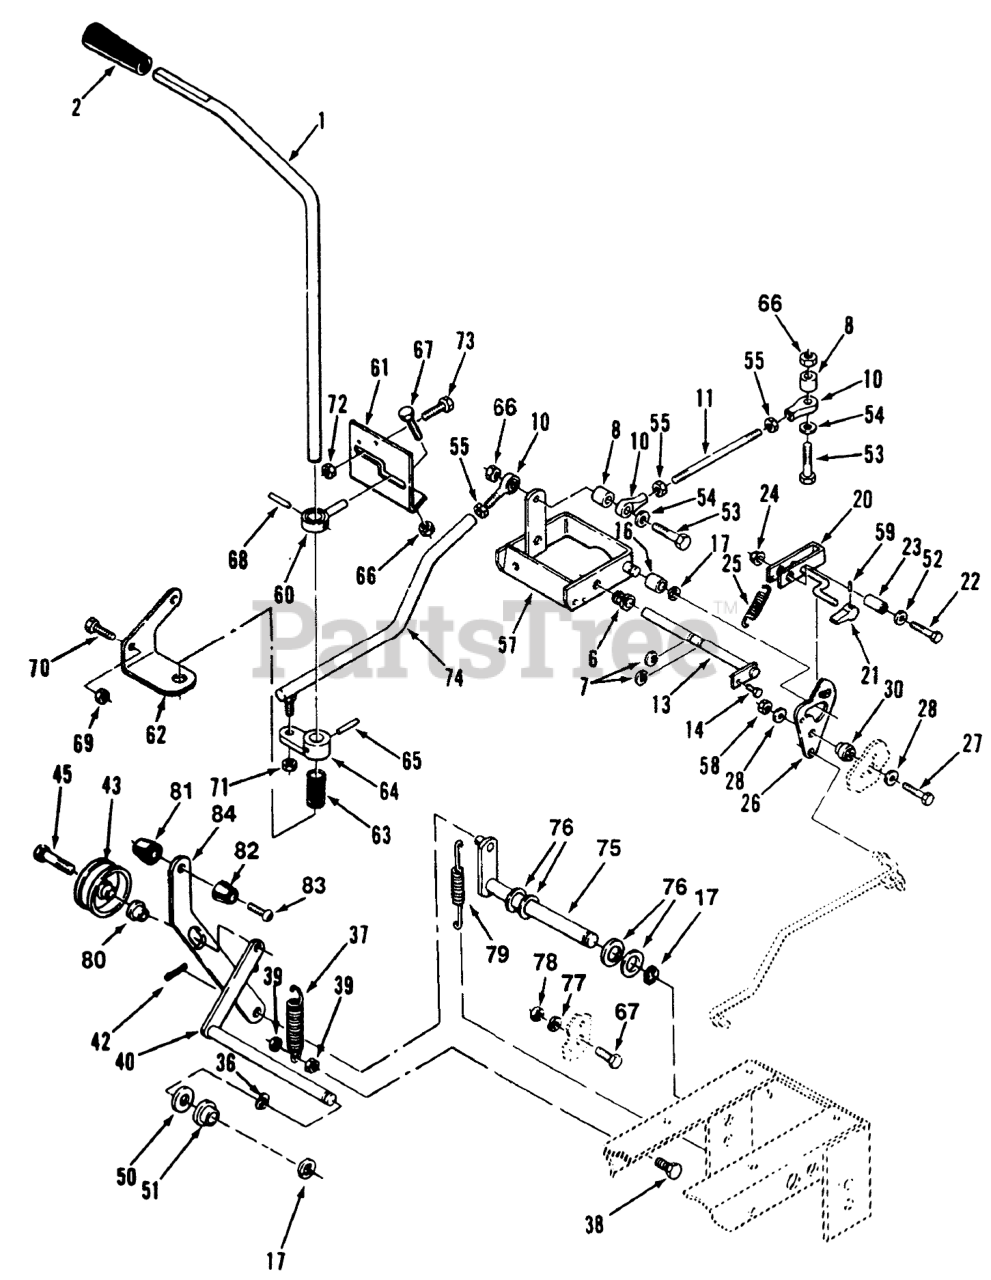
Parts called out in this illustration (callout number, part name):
1	ROD-MOTION CONTROL
2	Knob-Motion Control
6	NYLINER BUSHING
7	E Ring
8	Spacer
10	ROD END, 1/4-28
11	ROD-CONTROL
13	ASSY-ROD CAM PIVOT
14	SCREW
16	BEARING-CAM RETURN
17	E Ring
20	Lever-Parking Brake
21	KNOB-PARKING BRAKE
22	SCREW-HH
23	SPACER
24	LOCKNUT-FLANGE
25	Spring
26	Cam Plate
27	SCREW-HH
28	WASHER-FLAT
30	Spacer
36	WASHER-WAVE
37	SPRING-EXTENSION
38	SCREW-HH
39	NUT-LOCK
40	ASSY-ARM/ROD WA
42	Pin-Cotter
43	PULLEY-IDLER
45	BOLT-SPECIAL HEX
50	WASHER-FLAT
51	BUSHING-FLANGED
52	WASHER-FLAT
54	WASHER-FLAT
55	NUT-JAM
57	Cam Comtrol
58	NUT-LOCK, NI
59	PIN-SPIROL 3/32X5/8
60	GUIDE-CONTROL
61	Bracket-Control
62	Bracket-Control
63	SPRING-COMPRESSION
64	ARM-CONTROL
65	Pin-Spirol
66	NUT-LOCK, NI
67	SCREW-HH
68	SPIROL PIN 7/32X7/8
69	NUT-LOCK, NI
70	SCREW-HH
71	NUT-LOCK
72	NUT-LOCK, NI
73	SCREW-HH
74	ASSY-ROD & BALL JOINT
75	ASSY-BRAKE LEVER
76	WASHER-FLAT
77	WASHER-LOCK/EXT
78	NUT-JAM
79	SPRING-EXTENSION
80	SPACER-BRAKE LINK
81	KNOB
82	KNOB
83	BOLT-4
84	Handle
